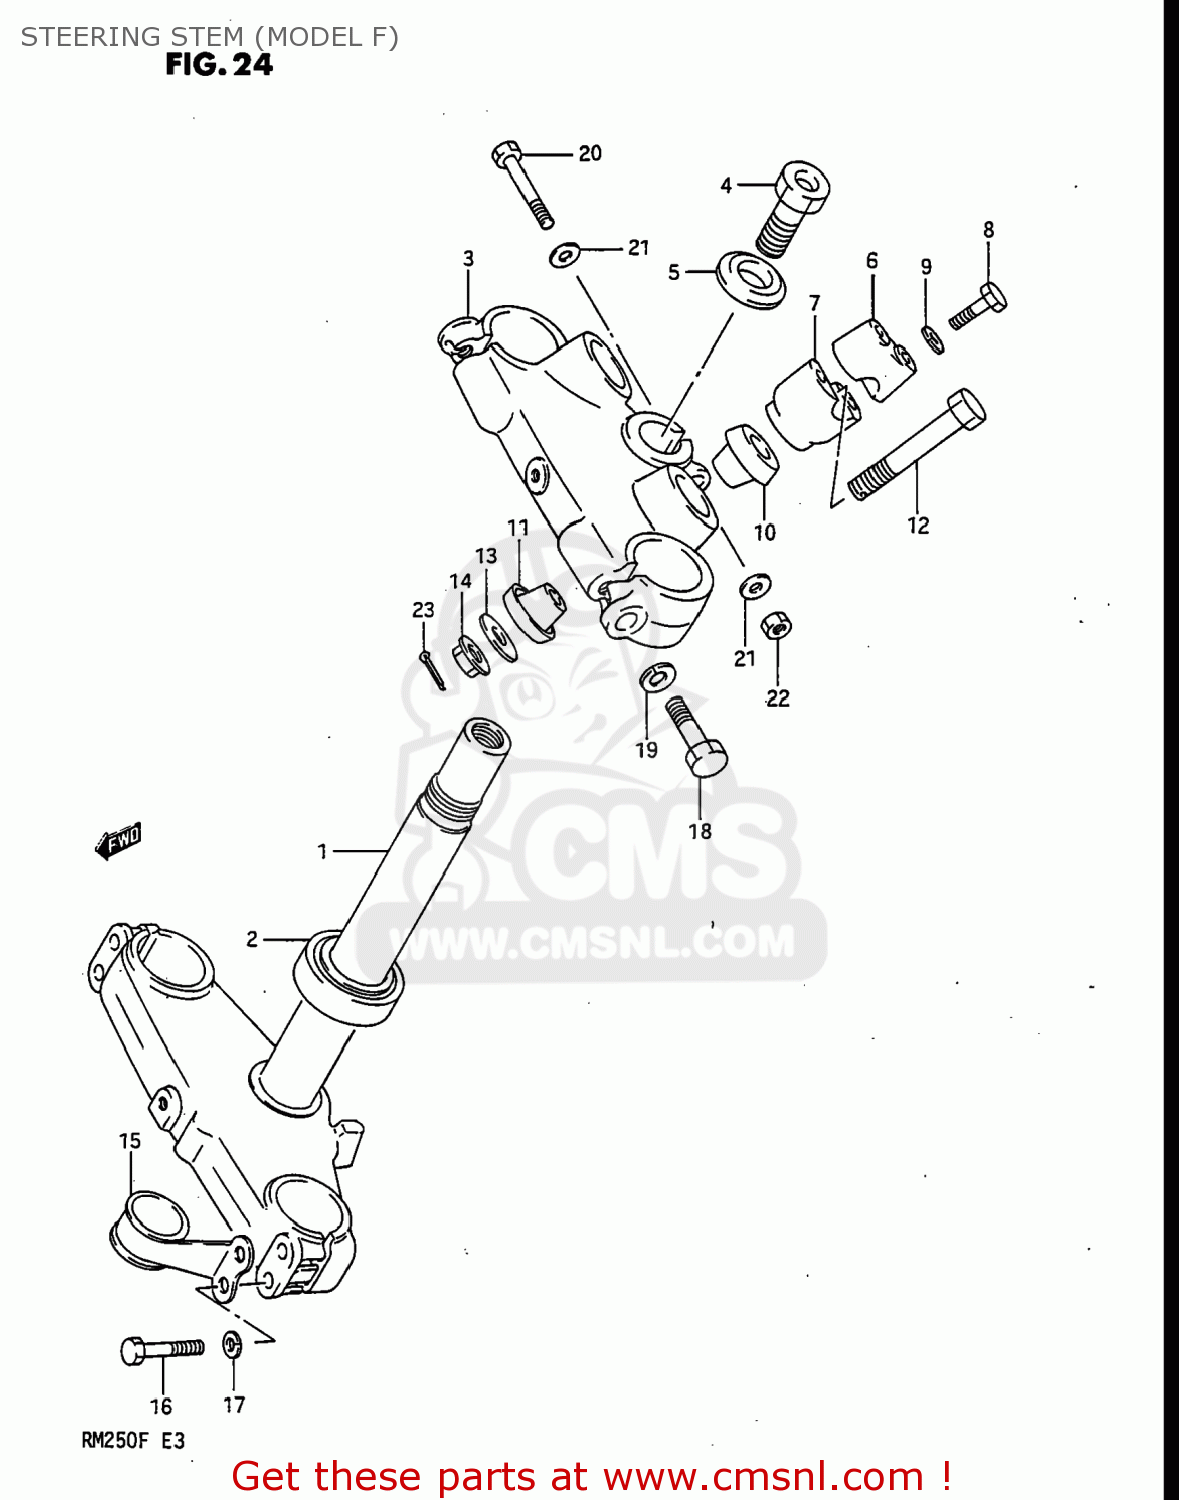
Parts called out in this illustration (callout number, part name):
1	STEM,STEERING
2	BEARING
3	HEAD,STEERING STEM
4	BOLT
5	WASHER
6	HOLDER,HANDLEBAR
7	HOLDER,HANDLE LWR
8	BOLT
9	WASHER,LOCK,8.
10	DAMPER,UPR
11	DAMPER,LWR
12	BOLT
13	WASHER,HANDLEBAR HOLDER
14	NUT
15	GUIDE,CABLE
16	BOLT 8X40
17	WASHER,LOCK,8.
18	BOLT
19	LOCK WASHER
20	BOLT 8X50
21	WASHER
22	NUT
23	COTTER PIN
